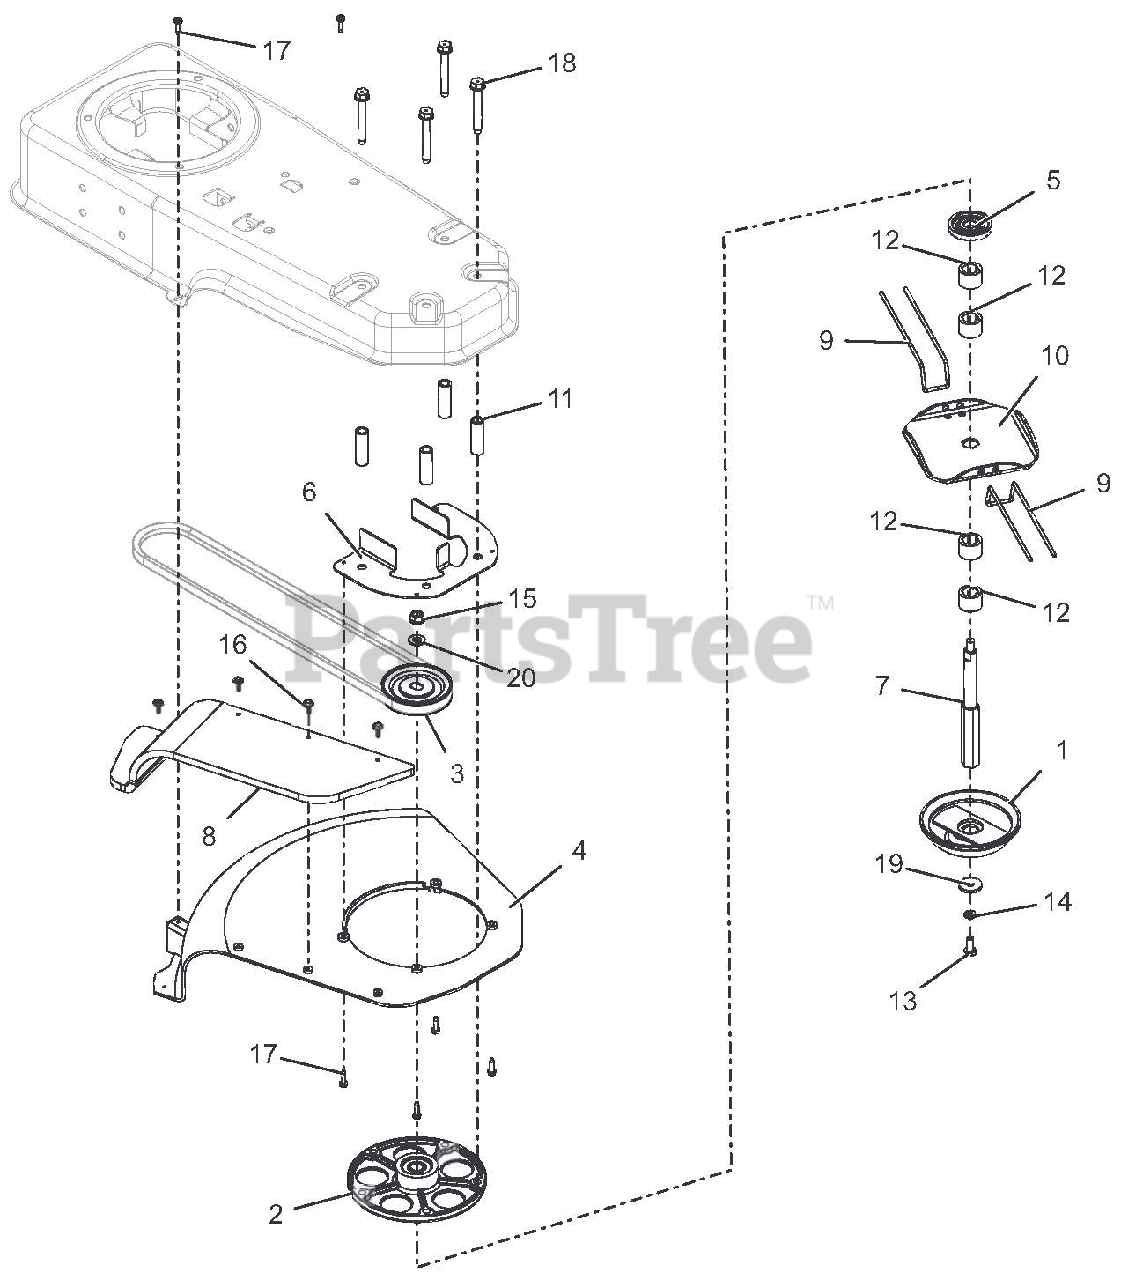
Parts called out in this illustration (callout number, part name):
1	WELDMENT, HEIGHT GUIDE
2	HOUSING - JACKSHAFT
3	PLY-V 3.50 OD X .87 WIDE (CUT)
4	SHIELD - TRIMMER
5	SHIELD - DUST
6	FINGER - BELT
7	SHAFT - CUTTER - HEX
8	GUARD - DEBRIS
9	LINE - CUTTER 18" LG PKG OF 6
10	CUTTER - DISK
11	BSHG-SPCR .406X.625X1.90
12	SPACER - HEX
13	@BLT-HEX .31-18X.75 GR5 YWZC
14	@WSHR-LK .31X.078 REG YWZC
15	NUT-LK-FLG .375-24 GR5 YWZC
16	SCR-TAP #10-16 X .625 HWH
17	SCR-TAP 10-24X.75 HWH TR YWZC
18	@SCR-TAP.375-16X2.75 HWH TR YZ
19	WSHR-FL-STL .344X1.125X.135
20	@WSHR-FL-STL.406X.812X.065 YWZ
